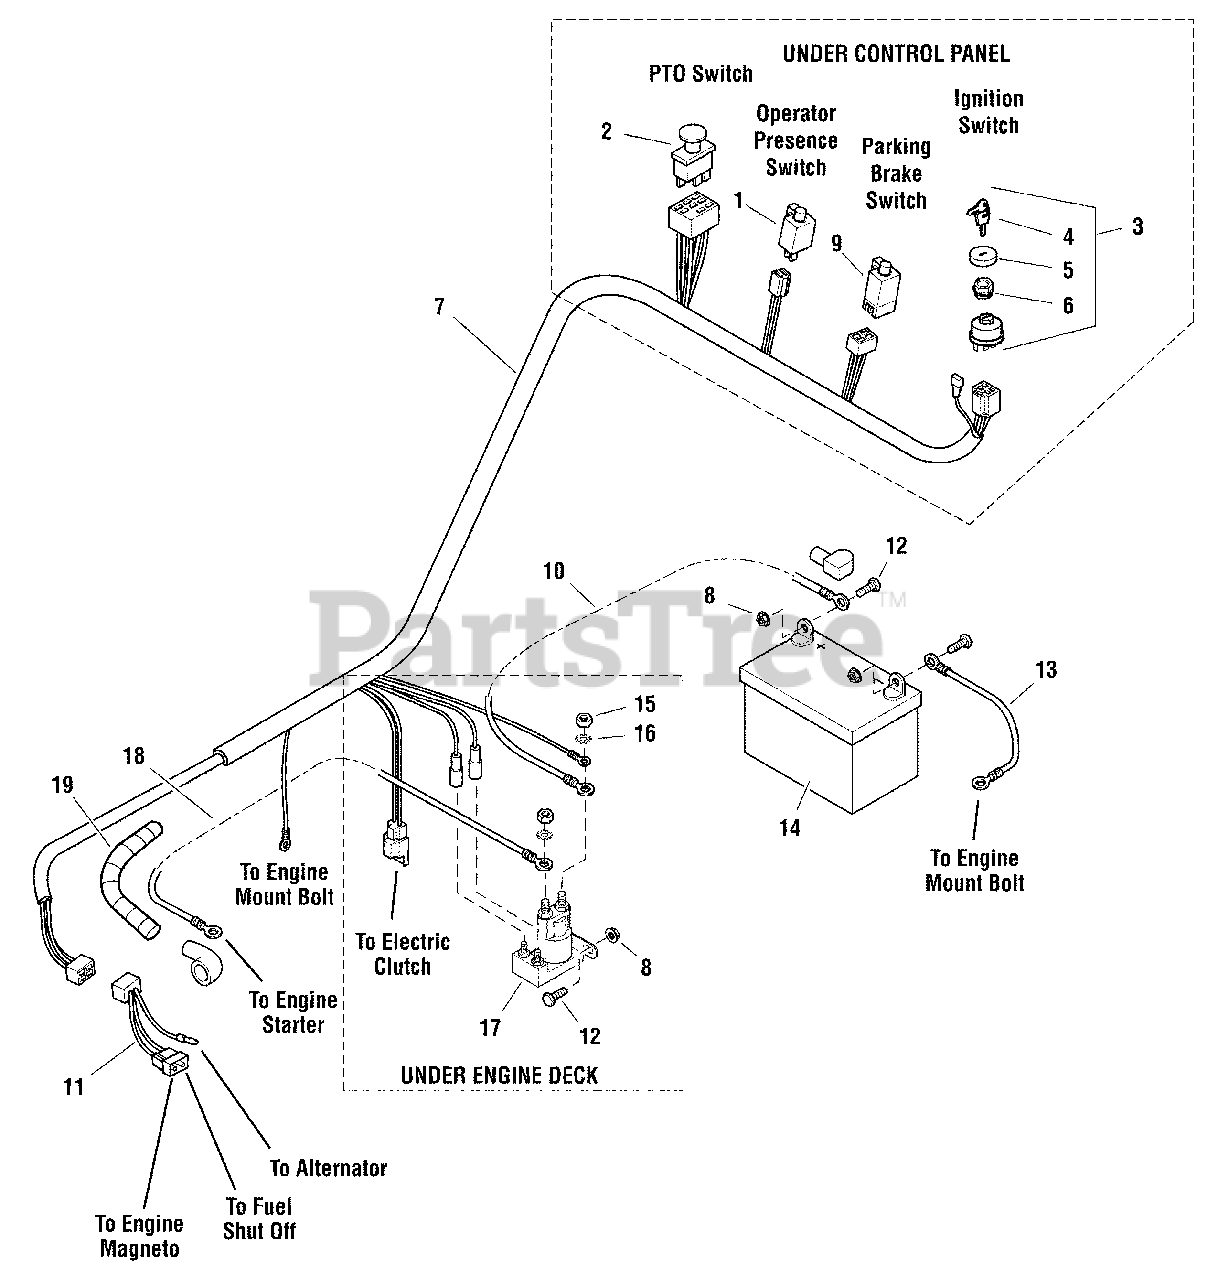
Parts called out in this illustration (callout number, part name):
1	SWITCH, PLUNGER NC
2	SWITCH, BLADE ENGAGEMENT
3	SWITCH ASMY-IGNITION INDAK NO KEYS
4	KEYS. BLISTER PK KIDS+MWRS DON'T MIX, USA Models Only
5	COVER, PLASTIC SNAP ON
6	NUT, PLASTIC
7	WIRE HARNESS, MAIN HYDROCUT/PACER
8	NUT, 1/4-20 HEX SERRATED FLANGE
9	SWITCH, PLUNGER, N.O./N.C.
10	BATTERY CABLE, POSITIVE, 22"
11	WIRE HARNESS, PACER 1732, JUMPER
12	BOLT, 1/4-20 X 3/4
13	BATTERY CABLE, NEGATIVE, 22"
14	BATTERY, WET ( BCIU1, 340 CCA)
15	NUT, HEX JAM 5/16-24
16	WASHER, LIGHT LOCK, 5/16
17	SOLENOID-4 POLE 12 VOLT DC (TROMBETTA)
18	BATTERY CABLE, POSITIVE, 35"
19	WIRE LOOM, 3/8" ID X 23 IN LONG
